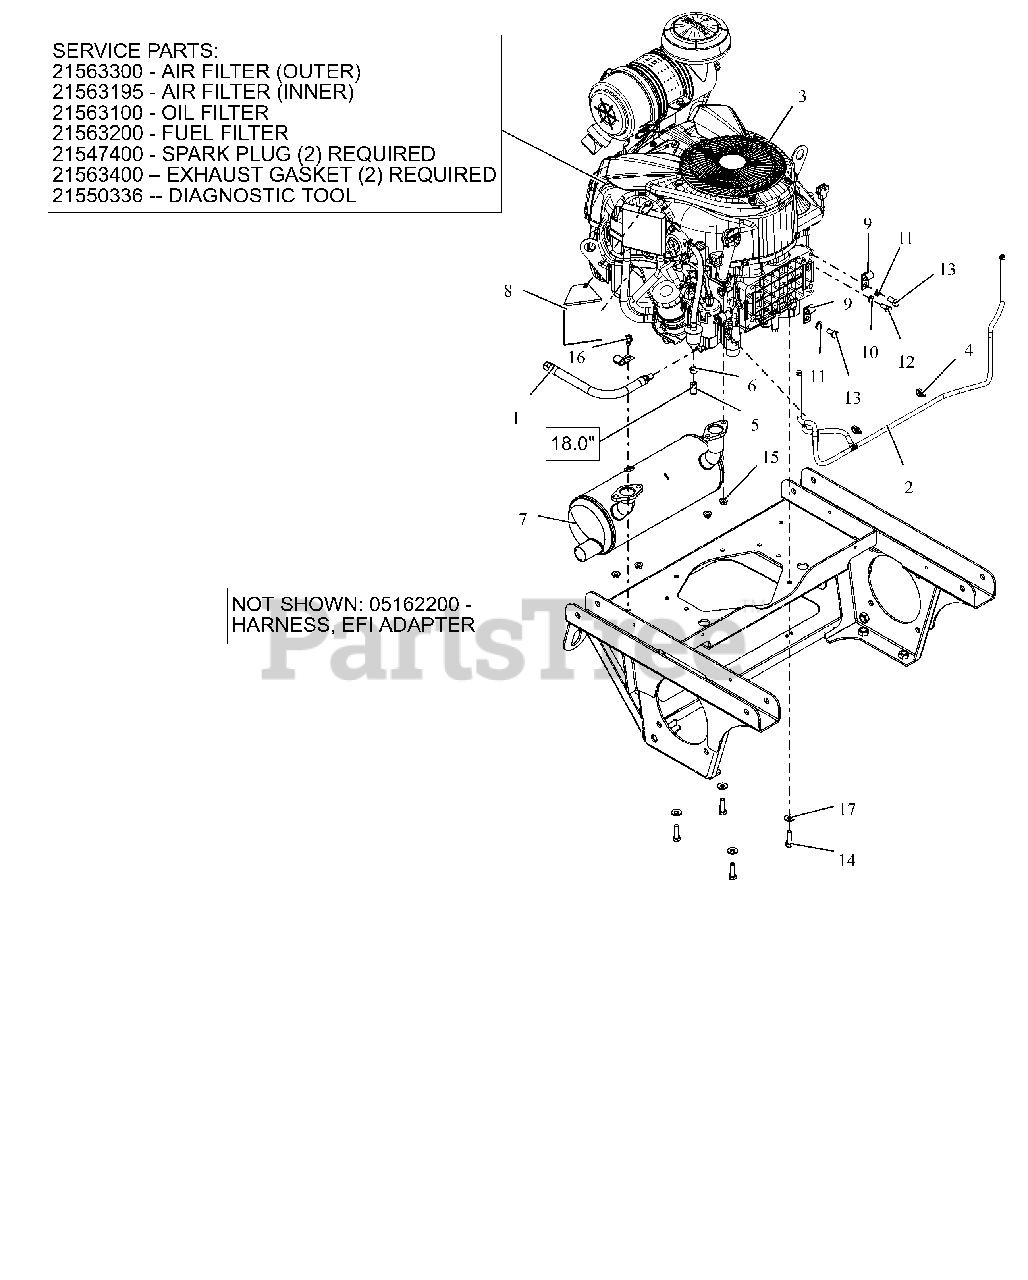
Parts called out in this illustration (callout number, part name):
1	HOSE, OIL DRAIN
2	ASM, YAMAHA VAPOR LINE
3	ENGINE, YAMAHA MX775V-EFI
3	AIR FILTER (OUTER) - YAMAHA
3	AIR FILTER (INNER) - YAMAHA
3	FILTER, OIL - YAMAHA 824
3	FILTER-FUEL YAMAHA 824
3	PLUG, SPARK
3	GASKET, MUFFLER YAMAHA 824
3	DIAGOSTIC TOOL, YAMAHA MXV
4	ROUTING CLIP (1/2" ID)
5	HOSE, .25 LOW-PERM BULK GAS
6	CLAMP, FUEL LINE
7	MUFFLER, YAMAHA
8	DEFLECTOR,YAMAH OIL COOLER AIR
10	WSHR,LK-REG .312X.078 ZCC
11	WSHR,LK-REG .375X.094 ZCC
12	BLT,HEX .31-18X.75 G5 ZCC
13	BLT,HEX .38-16X.75 G5 ZCC
14	BLT, HEX .38-16X1.25 G5 ZCC NT
15	NUT-LK-TOP-FLG M8 ZCC
16	SCR,TAP .375-16X.50 HWH TR ZCC
17	WASHER, 3/8" SPRING DISC
